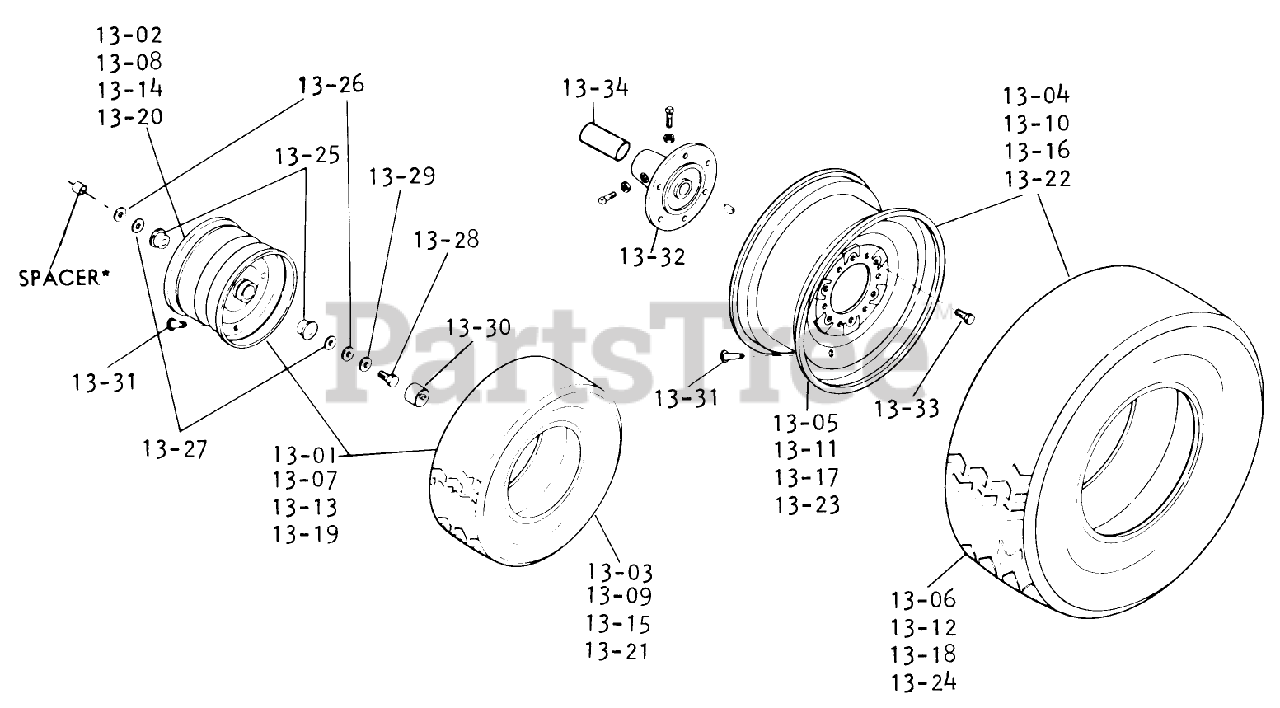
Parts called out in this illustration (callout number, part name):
13-02	BULLT 322
13-09	TIRE 18 X 8.50 X 8
13-14	BULLT 322
13-16	ORDER 110006 OR 110007
13-18	Rear Tire 27 x 8.50-15 Cleat
13-21	TIRE 18 X 8.50 X 8
13-22	Rear Wheel Tire Cleat
13-26	Washer-. 050" Shim
13-27	Washer-. 015" Shim
13-28	Bolt 3/8-16 x 7/8
13-29	WASHER
13-31	VALVE
13-33	BOLT-LUG, WHEEL
